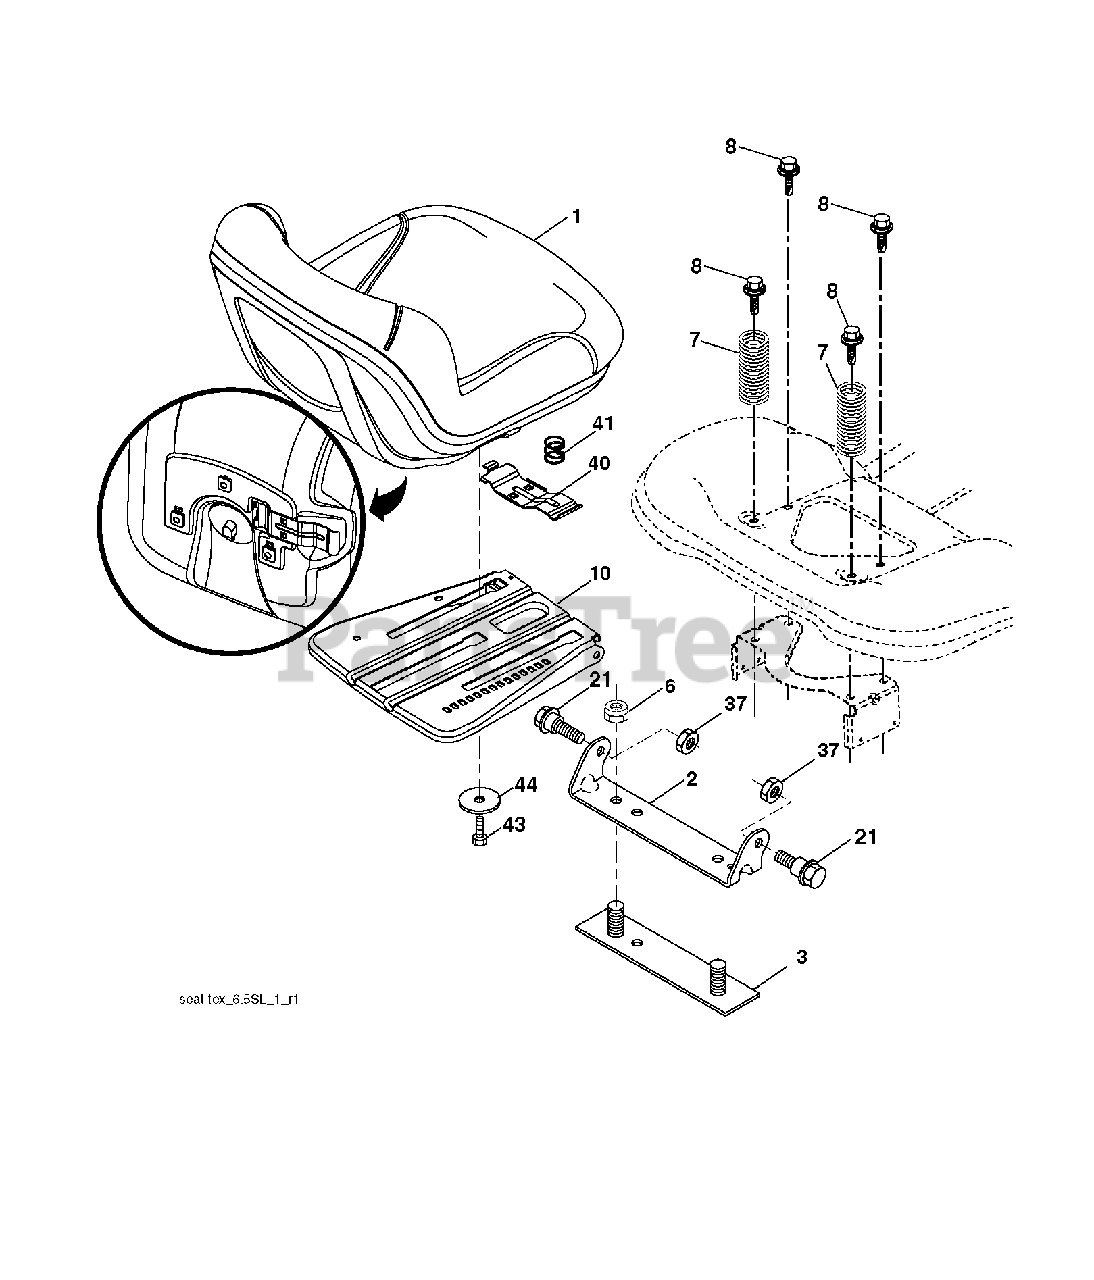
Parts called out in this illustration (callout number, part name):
1	SEAT.TH150.MS498.GRY.HUSQ.TEX
2	BRKT.PIVOT.FENDER
3	STRAP
6	NUT
7	SPRING COMPRESSION
8	BOLT, 5/16-18 X 1 3/4
10	PAN.ASM.SEAT.3PT
21	BOLT.SHOULDER.5/16-18
37	NUT.71038.31-18.HEX.NYLOCK
40	HANDLE.SLIDE.SEAT.TEX.BLACK
41	SPRING.LATCH.SEAT.TEX
44	WASHER 13/32 X 2-3/8 X 12GA
